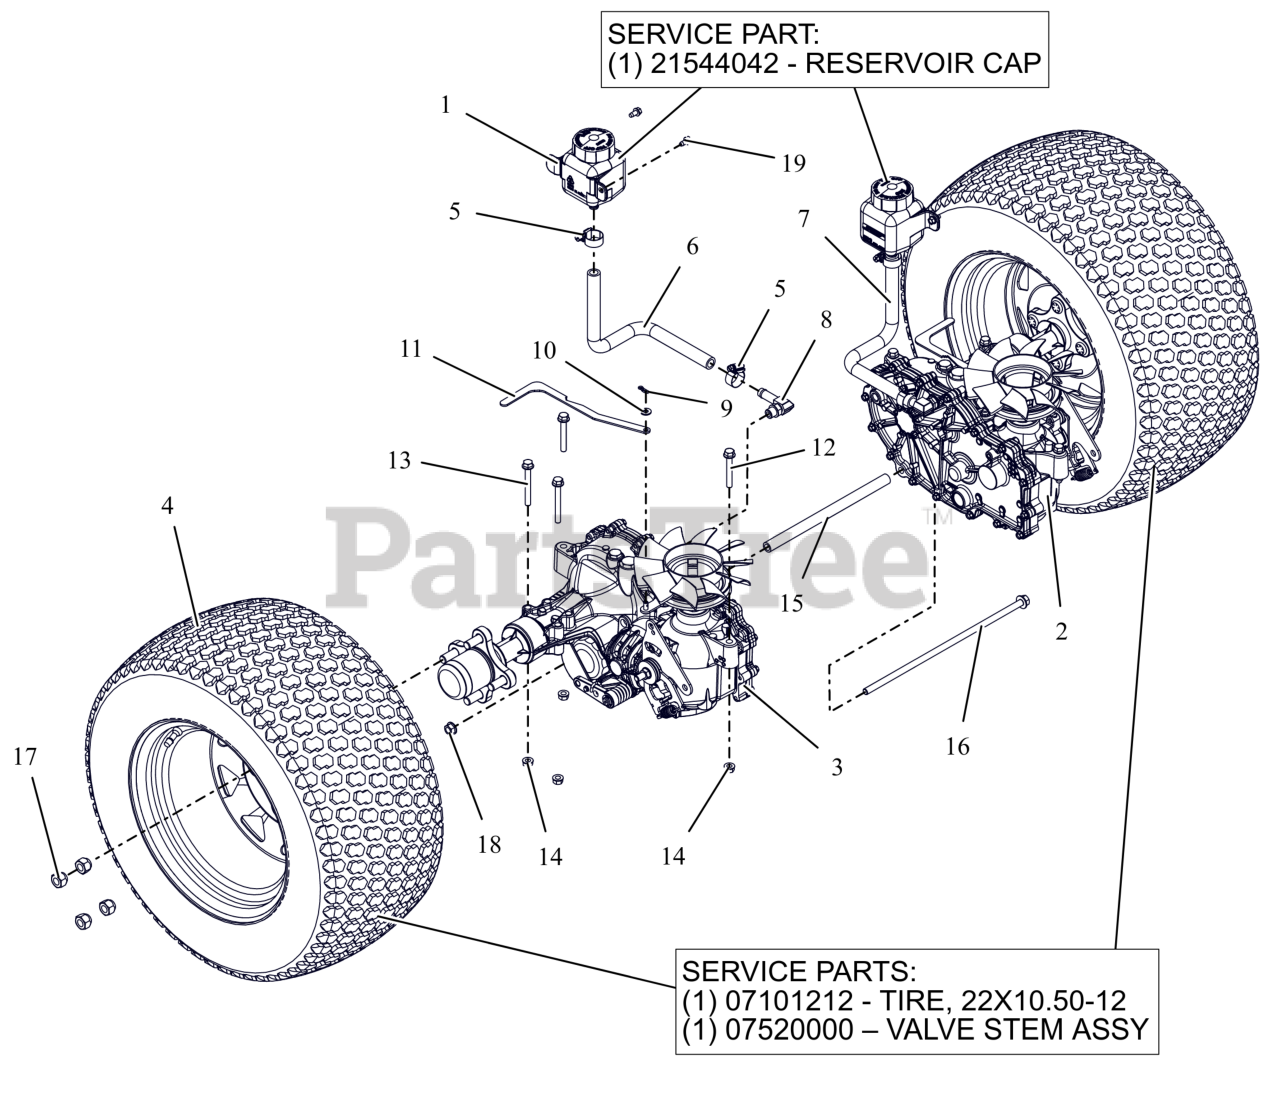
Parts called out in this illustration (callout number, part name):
1	TANK, EXPANSION
1	CAP, HYDRO RESERVOIR REPLAC.
2	TRANSAXLE, ZT3100 - LH
3	TRANSAXLE, ZT3100 - RH
4	ASM, WHL/TIRE 22X10.5-12 LG BLK
4	TIRE, 22X10.50-12
4	VALVE STEM ASS'Y
4	TUBE 22,23&24X8.50/9.50/10.00/10.50/12.00-12
5	CLAMP,.88 DIA. HOSE
6	HOSE, FORMED EXPANSION -HD RH
7	HOSE, FORMED EXPANSION -HD LH
8	FITTING, HYD (90 DEG)
9	PIN, HAIR #225 .072X1.09
10	WSHR,FLT .281X.625X.065 ZCC
11	BRKT, VALVE DUM
12	BLT,HEX-FLG .31-18X2.25 G5 ZCC
13	BLT,HEX-FLG .31-18X2.75 G5 ZCC
14	NUT,LK-CTR-FLG .31-18 GF ZCC
15	SPCR, TRANSAXLE .406 ID X .630 OD X 9.95LG (BLACK)
16	BLT, HEX-FLG 0.375-16X13 GR5 ZC120
17	NUT, WHEEL .50-20 ZCC
18	NUT-LK-TOP-FLG .38-16 ZC120
19	SCR-TAP .25-20X.50 HWH ZCC
